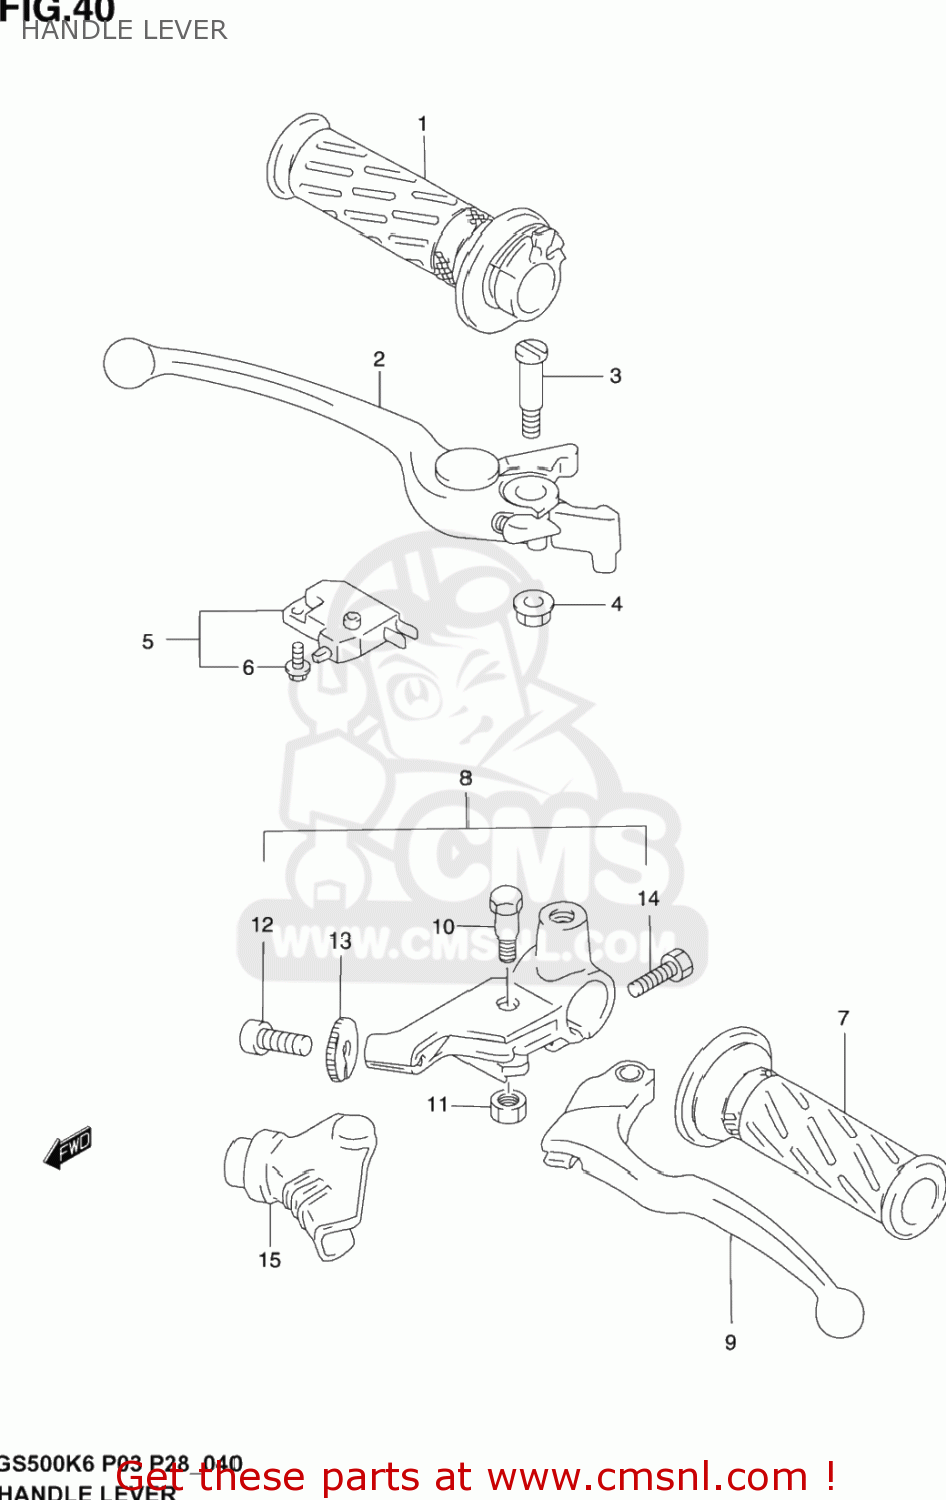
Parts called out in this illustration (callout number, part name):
1	GRIP, THROTTLE
2	GRIP, BRAKE
3	BOLT, PIVOT
4	NUT
5	SWITCH ASSY,ST
6	SCREW
7	GRIP LH
8	LEVER ASSY,CLUTCH
9	LEVER,CLUTCH
10	BOLT,LEVER SET
11	NUT
12	ADJUSTER,CABLE
13	NUT,CABLE ADJUSTER
14	SCREW
15	COVER,CLUTCH LEVER
